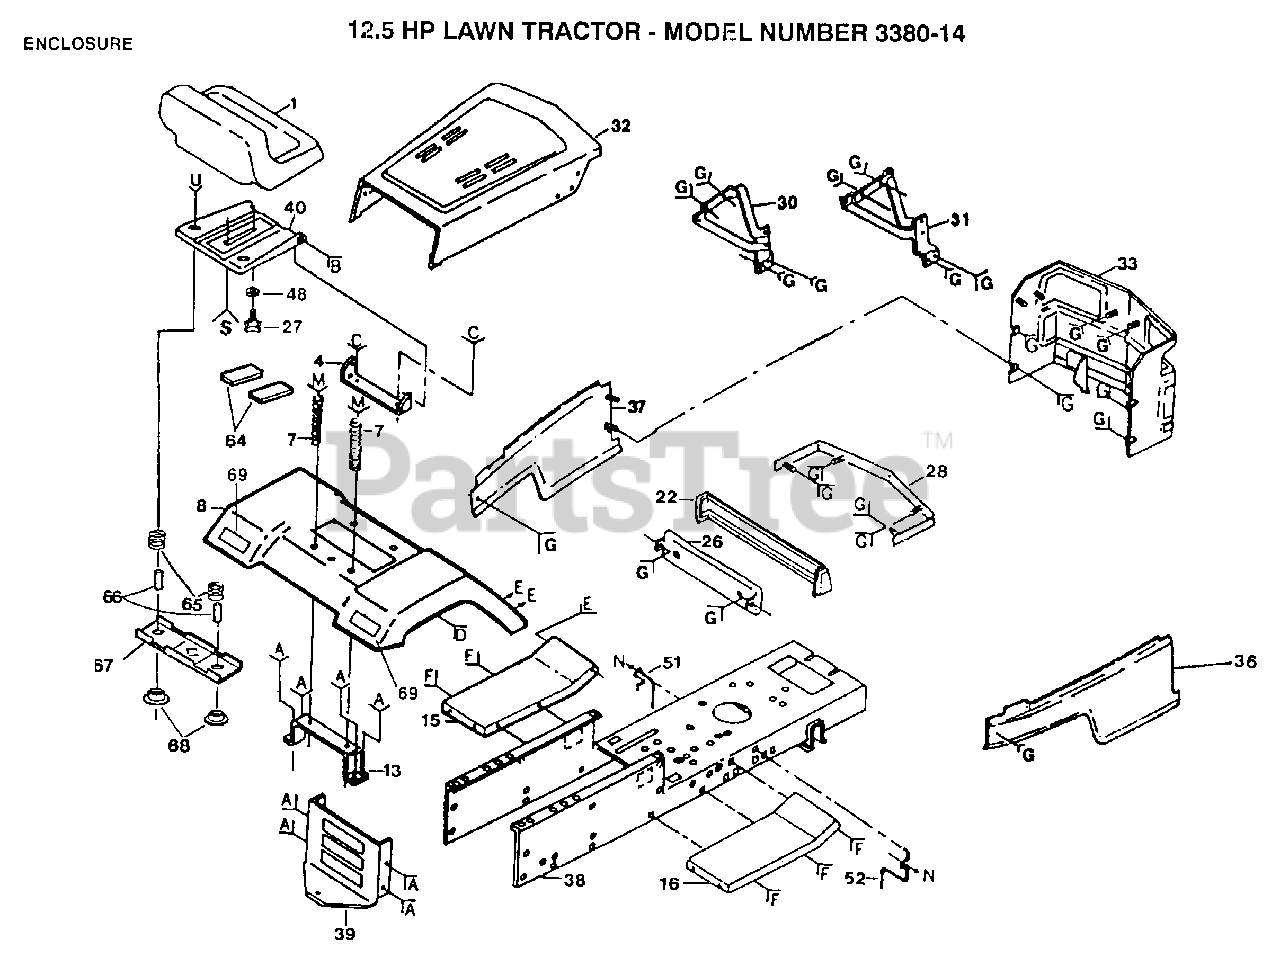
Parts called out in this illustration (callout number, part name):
7	SPRING COMPRESSIO
27	"KNOB 1/2"" YT"
30	"HINGE,HOOD,LH T"
31	"HINGE,HOOD,RH T"
36	"PANEL,SIDE RH"
37	"PANEL,SIDE LH"
38	CHASSIS ASS'Y
39	DRAWBAR LT/YT
48	WASHER
51	BELT GUIDE
52	BELT GUIDE
64	STRIP FORM
65	SPRING COMPRESSED
66	SPACER SPLIT
67	BRKT SWITCH
68	BUSHING
